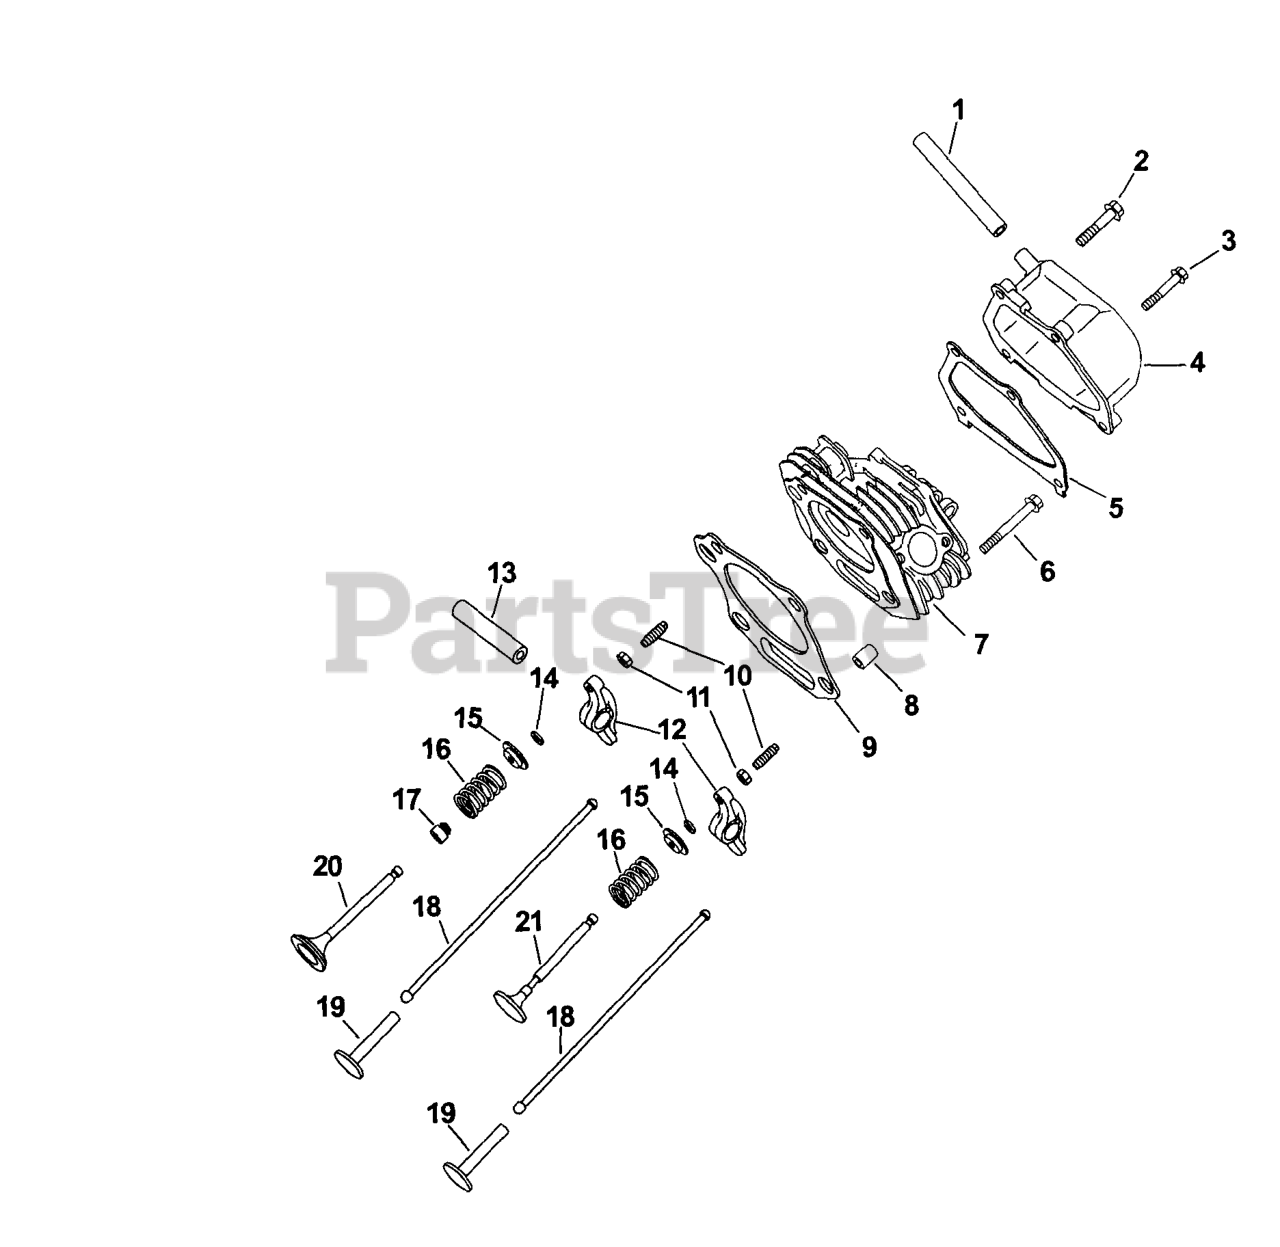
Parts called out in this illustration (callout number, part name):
1	HOSE, BREATHER -USE 63 326 13-S
2	SCREW, VALVE COVER
3	SCREW, VALVE COVER
4	VALVE COVER ASSEMBLY
5	GASKET, VALVE COVER
6	SCREW, CYL HEAD
7	CYLINDER HEAD
8	PIN, DOWEL
9	GASKET, CYLINDER HEAD
10	SCREW, VALVE ADJ
12	ARM, ROCKER
13	SHAFT, ROCKER ARM
14	VALVE, COTTER-(#DSC)
15	CAP, VALVE SPRING
16	SPRING, VALVE
17	SEAL, VALVE STEM
19	LIFTER, VALVE
20	VALVE, INTAKE
21	VALVE, EXHAUST
